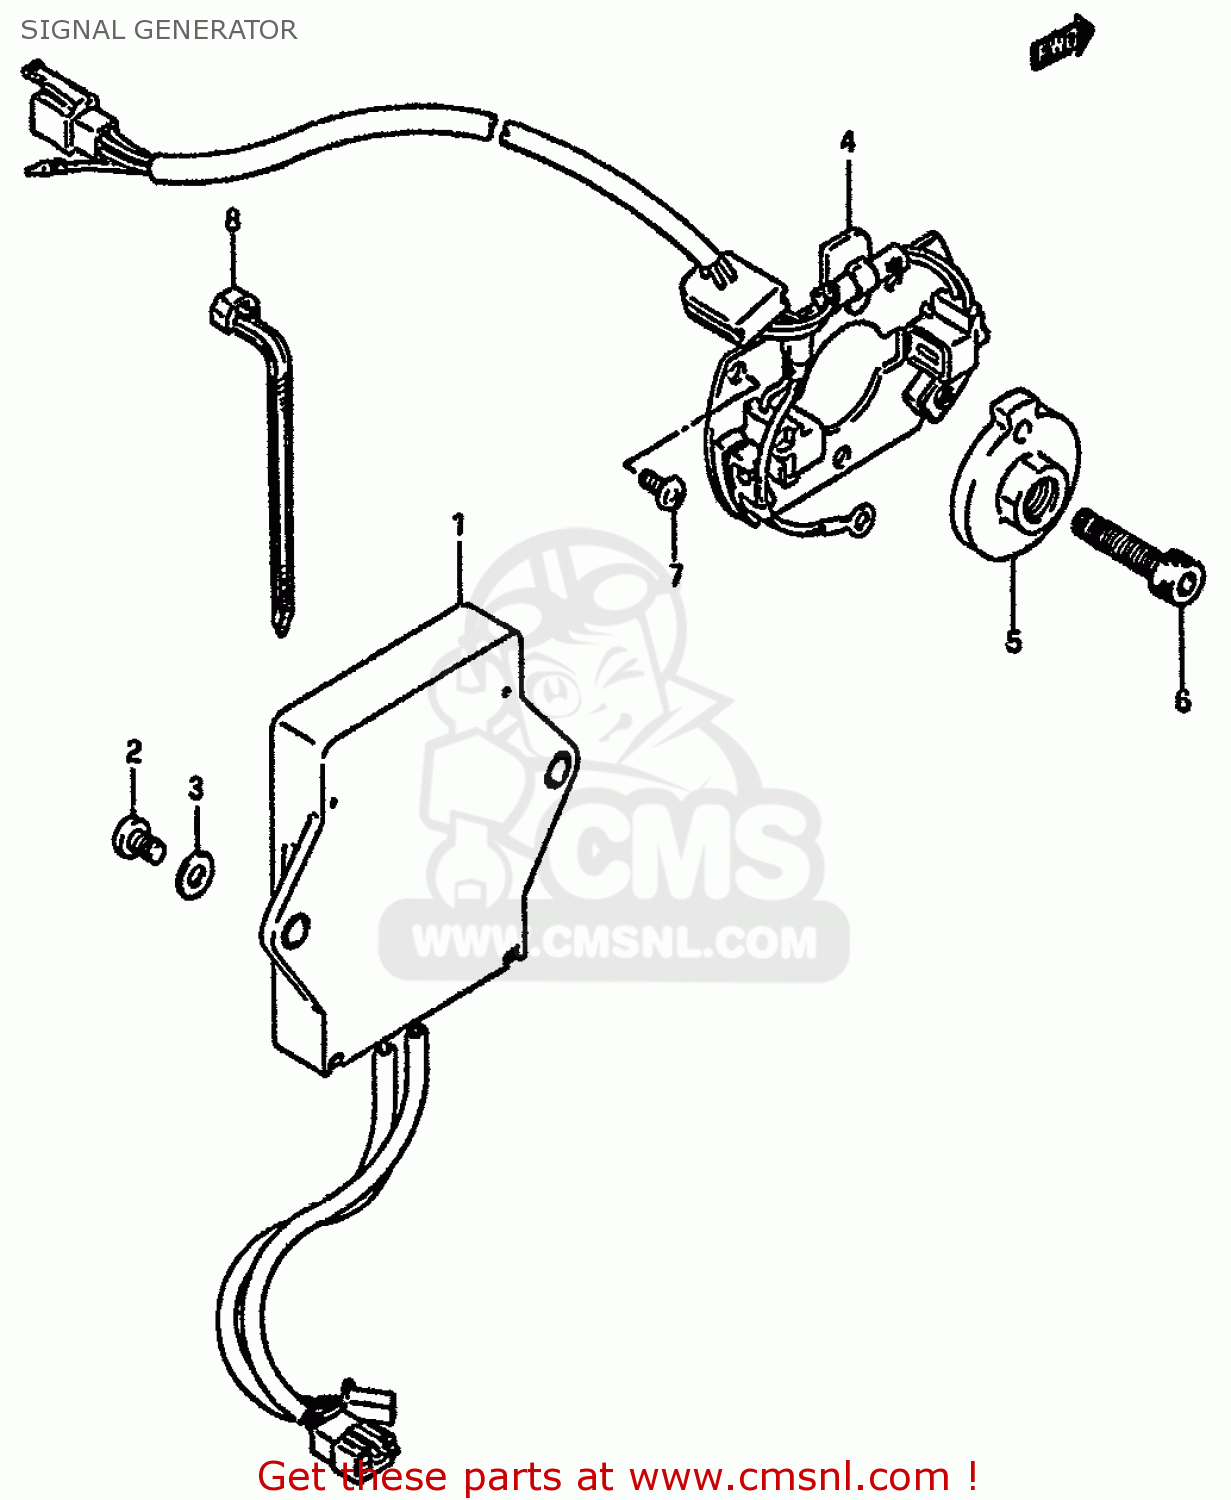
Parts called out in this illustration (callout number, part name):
1	IGNITER UNIT
2	SCREW
3	WASHER, LOWER
4	GENERATOR ASSEMBLY,SIGNAL
5	ROTOR COMP,SIGNAL
6	BOLT
7	SCREW
8	CLAMP(L:95)
